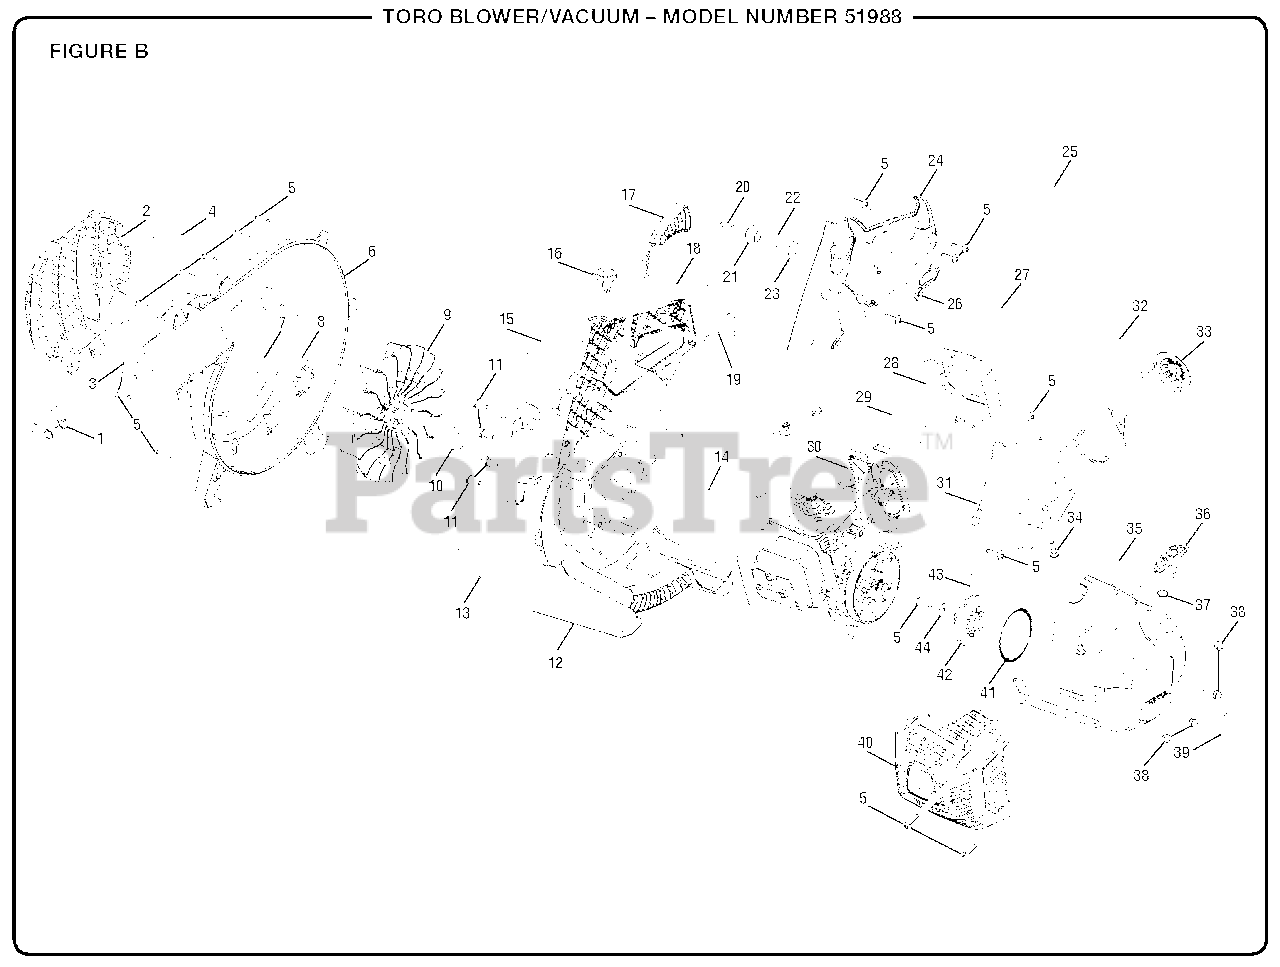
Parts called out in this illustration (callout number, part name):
1	Vacuum Door Hinge
2	Vacuum Door
3	Warning Icon Label
4	Logo Label (Right)
5	Screw (10-14 x 3/4 in)
6	Outer Volute Assembly
7	Flanged Lock Nut (M8 x 125, LH)
8	Mulching Blade
9	Blower Fan
10	Washer (ID8 x OD34 x 3t)
11	Screw (M5 x 16mm, Torx Pan Hd)
12	Engine Shroud Assembly
13	Combustion Warning Label
14	Logo Label (Rear)
15	Tube Removal Label
17	Throttle Lever
18	Throttle Cable Assembly
19	Ground Wire Assembly
20	Screw (10-14 x 18 mm, T25 Torx Hd TF)
21	Throttle Trigger Activator
22	Wavy Washer (217OD x 165ID x 15t)
23	Washer (225OD x 16ID x 05t)
24	Handle Cover Assembly
25	Icon Warning Strip
26	Cruise Control Lever
27	Starting Instructions Label
28	Air Box Cover Assembly
29	Air Filter
30	Power Head Assembly
31	Fuel Tank Assembly
32	E85 Label
34	Screw (M5 x 16 mm)
35	Starter Housing Assembly
36	Starter Grip
38	Screw (M5 x 20 mm, Torx Pan Hd)
39	Logo Label (Left)
40	Muffler Cover
41	Spring Holder Assembly
42	Starter Pulley
43	Starter Rope
44	Washer (ID62 x OD18 x 15t)
